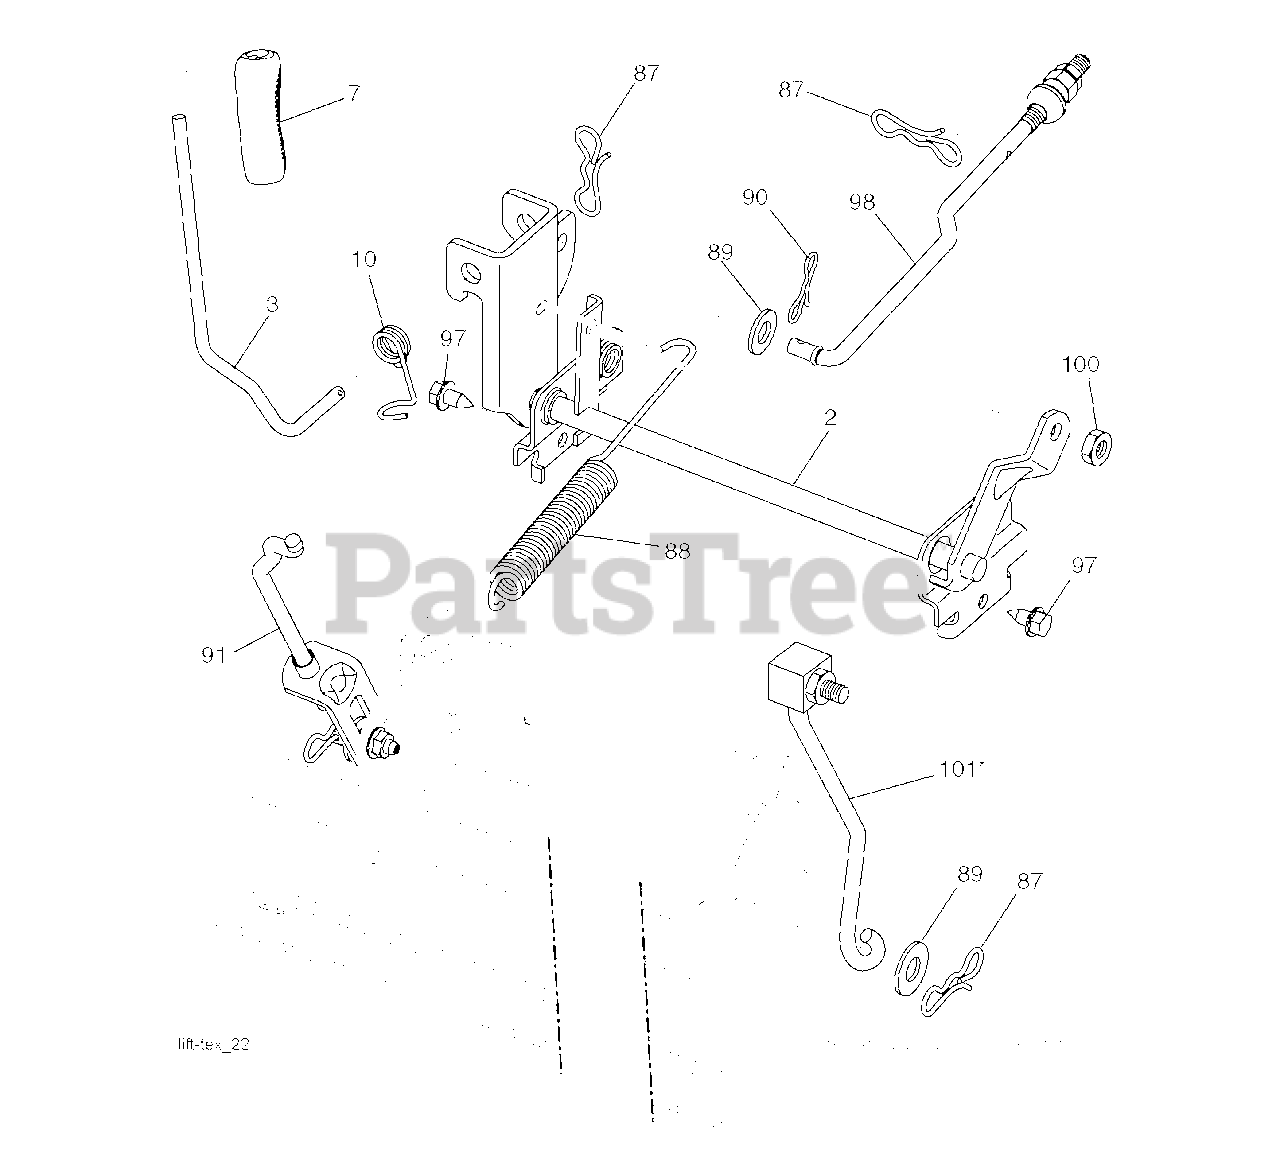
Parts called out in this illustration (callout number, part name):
2	SHAFT.ASM.CROSS.LIFT
3	LEVER.LIFT.HANDLE.LT
7	GRIP.HANDLE.LIFT.PVC.BLACK
10	SPRING.TORSION.LIFT.HANDLE
87	PIN.COTTER.7/16.BOW TI
88	SPRING.LIFT.ASSIST
89	WASHER.CLEAR.ZINC
90	PIN.COTTER.5/16.BOW TI
91	LINK.ASM.LIFT.REAR
97	SCREW, 3/8-16X3/4
98	LINK.ASM.SUSP.FRONT.MW
100	LOCKNUT
101	LINK.ASM.LIFT.FIXE.38/42/46"
